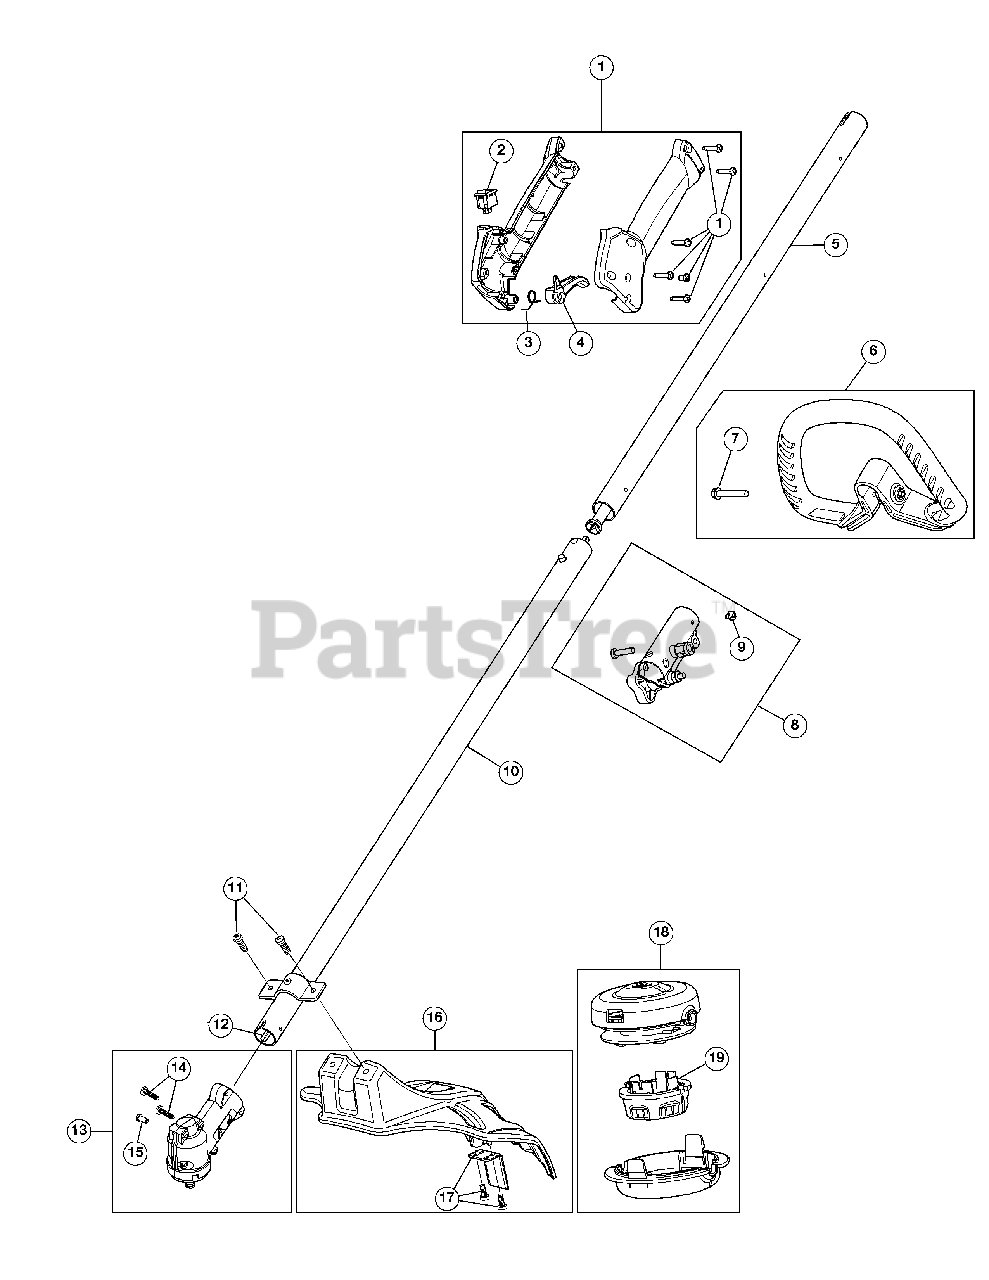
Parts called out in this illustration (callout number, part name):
1	Throttle Housing Assembly (Incl. 2 - 4)
2	Trigger Switch Assembly
3	Throttle Trigger Spring
4	Throttle Trigger
5	Upper Drive Shaft Assembly
6	D-Handle Assembly (Incl. 7)
8	Split Boom Coupler (Incl. 9)
9	Coupler Anti-Rotation Screw
10	Lower Drive Shaft Housing
11	Shield Mounting Screws
12	Lower Flexible Drive Shaft
13	Gearbox Assembly (Incl. 14 and 15)
14	Gearbox Mounting Hardware
15	Gearbox Anti-Rotation Screw
16	Shield Assembly (Incl. 17)
17	Blade Assembly
18	Cutting Head Assembly (Incl. 19)
19	Bump Knob
